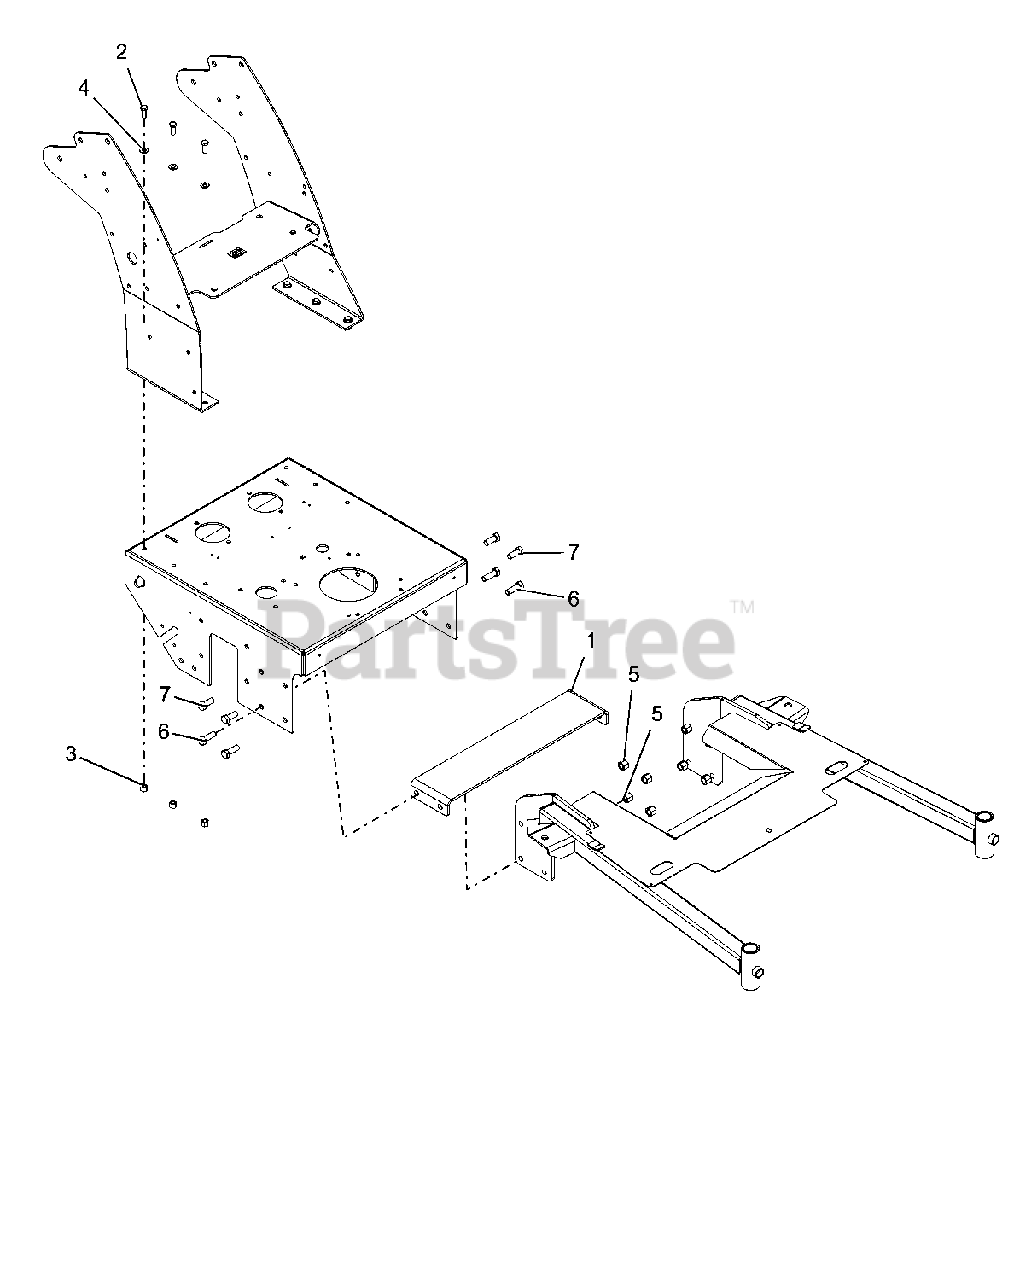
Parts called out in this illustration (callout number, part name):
1	PLATE, ENGINE BED FRONT 48/52-RED
2	BLT-HEX .38-16X1.00 GR5 YWZC
3	NUT-LK-NYL .38-16 YWZC
4	WSHR-FL-STL.406X.812X.065 YWZ
5	NUT-LK-NYL .50-13 YWZC
6	BLT-HEX .50-13X1.50 GR5 YWZC
7	BLT-HEX .50-13X1.25 GR5 YWZC
